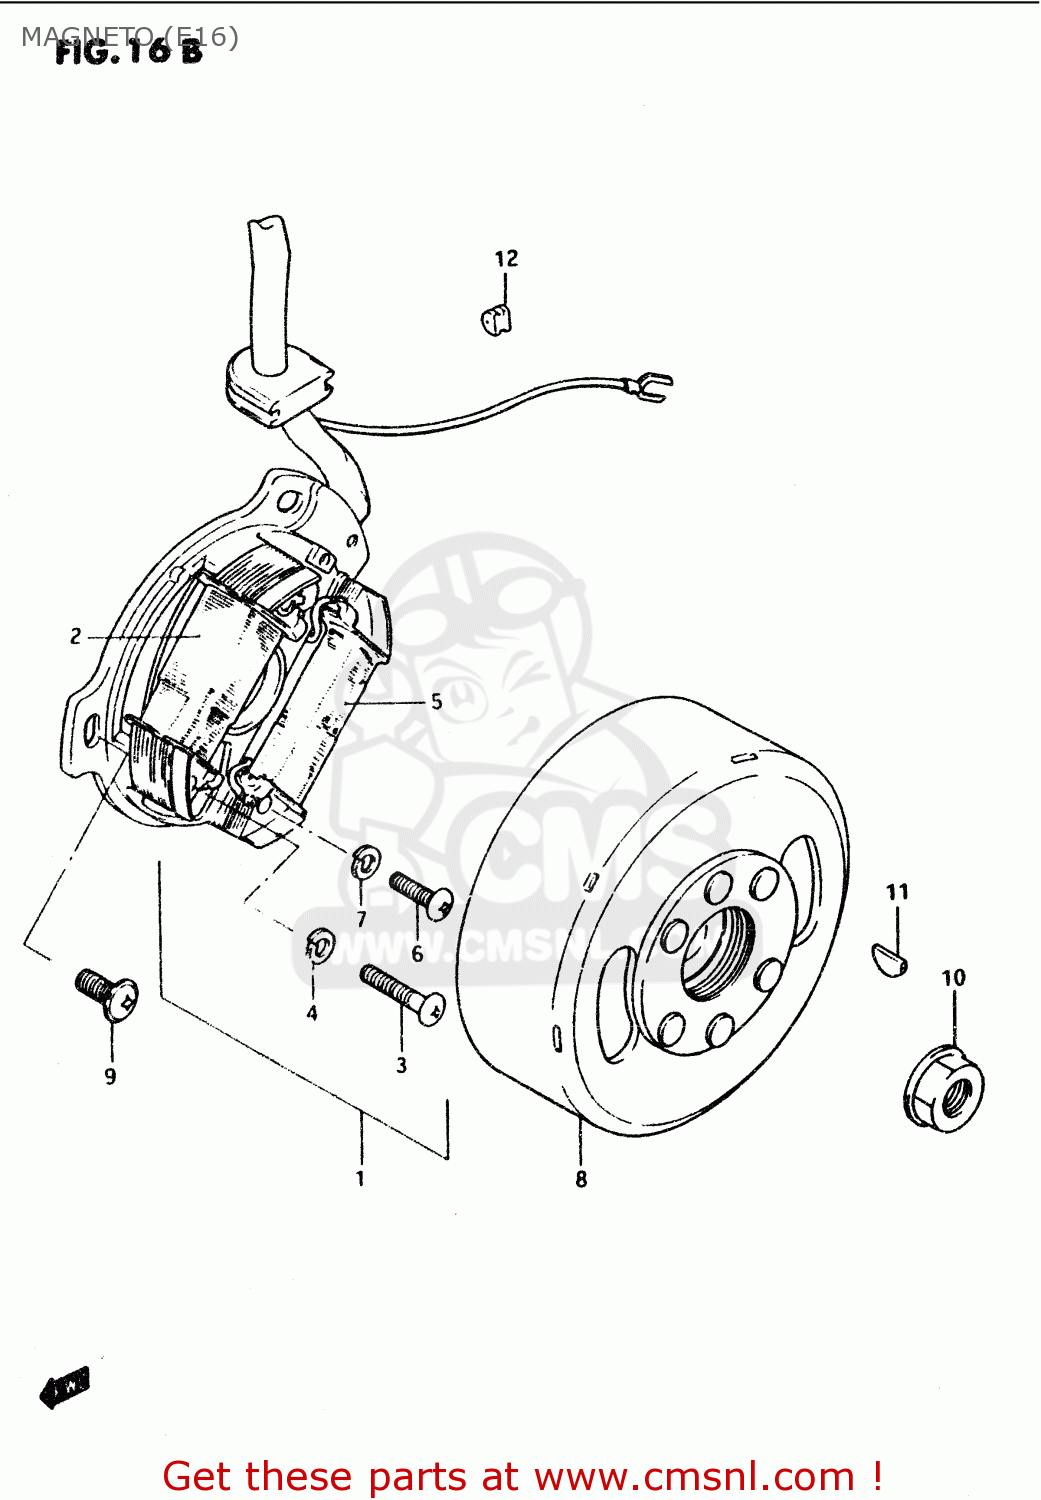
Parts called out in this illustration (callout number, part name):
1	STATOR ASSY
2	COIL, LIGHTING
3	SCREW
4	WASHER,LOCK
5	COIL,PRIMARY
6	SCREW
7	WASHER,LOCK
8	ROTOR ASSY
9	SCREW
10	NUT
11	KEY
12	GROMMET,NEUTRAL LEAD WIRE
